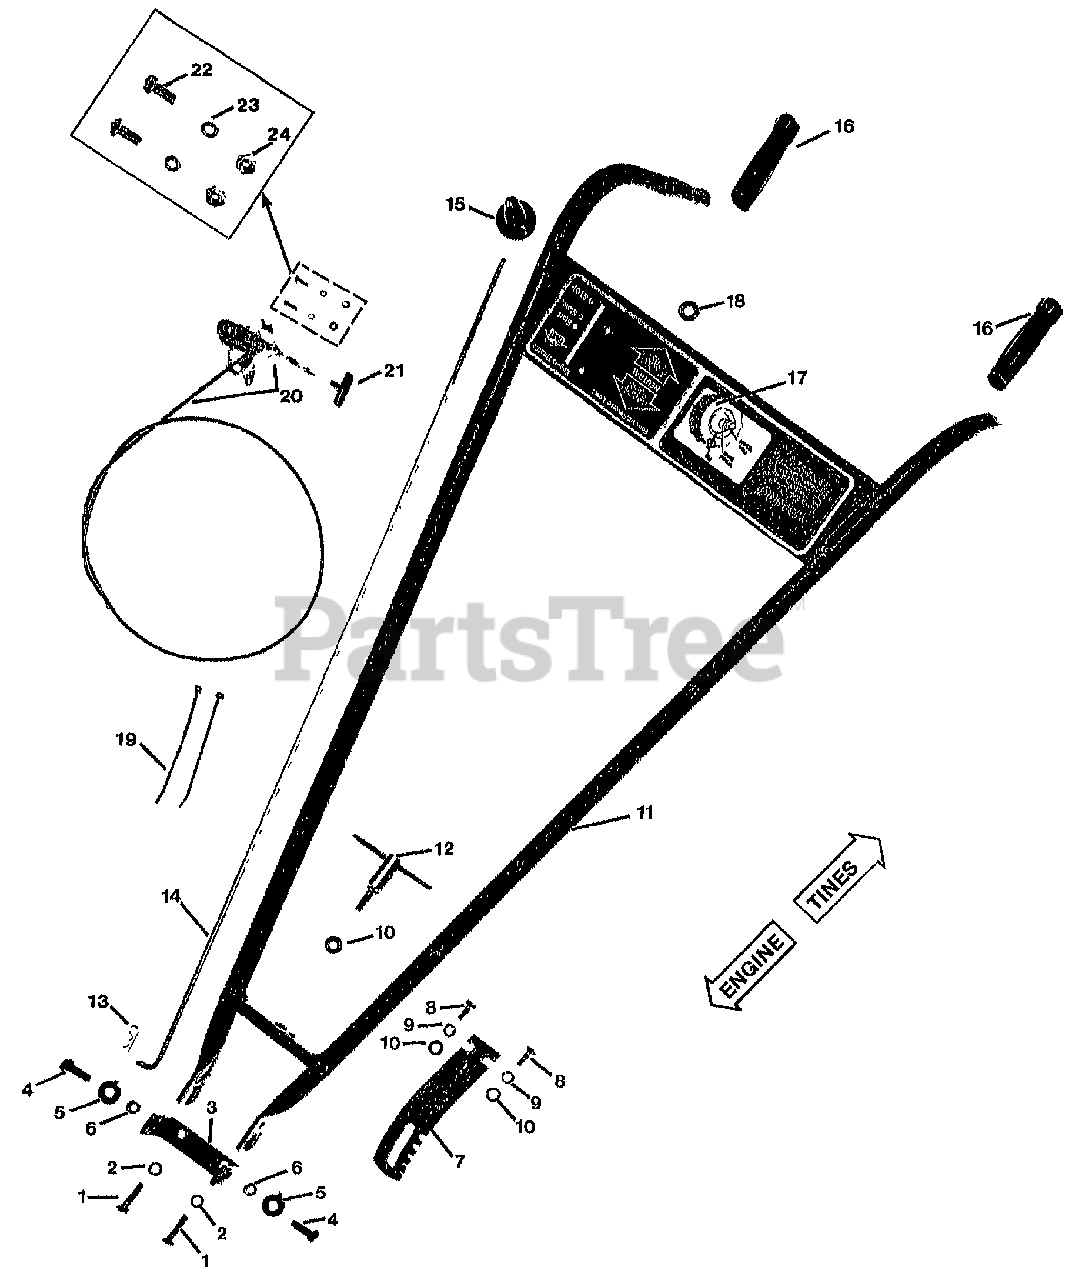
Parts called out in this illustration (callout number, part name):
1	SCR-HH 5/16-18X1.25 G5ZP
2	WASHER-LK .312 ZP
3	BRKT-HANDLEBAR PIVOT
4	SCR-HH 3/8-16X1.0 G5 ZP
5	WASHER-TAB #
6	NUT-LOCK 3/8-16 NYLON ZP
7	PLATE-HANDLEBAR ADJUST
8	SCR-HH 3/8-16X1.0 G5 ZP
9	WASHER-LK .375 @ DEPL
10	WASHER-1.0X.438X.104 ZP
11	ASSM-HANDLEBAR REPLACE
12	ASSM-CLAMP
13	PIN-CLIP .08
14	ASSM-DRIVE CONTROL ROD
15	KNOB-DRIVE CNTRL ROD
16	GRIPS-HANDLEBAR
17	DECAL-CONTROL PANEL
18	GROMMET-PLASTIC
19	TIE-RED
20	CABLE-THROTTLE & KNOB
21	KNOB-THROTTLE CABLE
22	SCR-RH M10-32X.5 MACH
23	WASHER-LK M10
24	NUT-HH M10-32X.125
